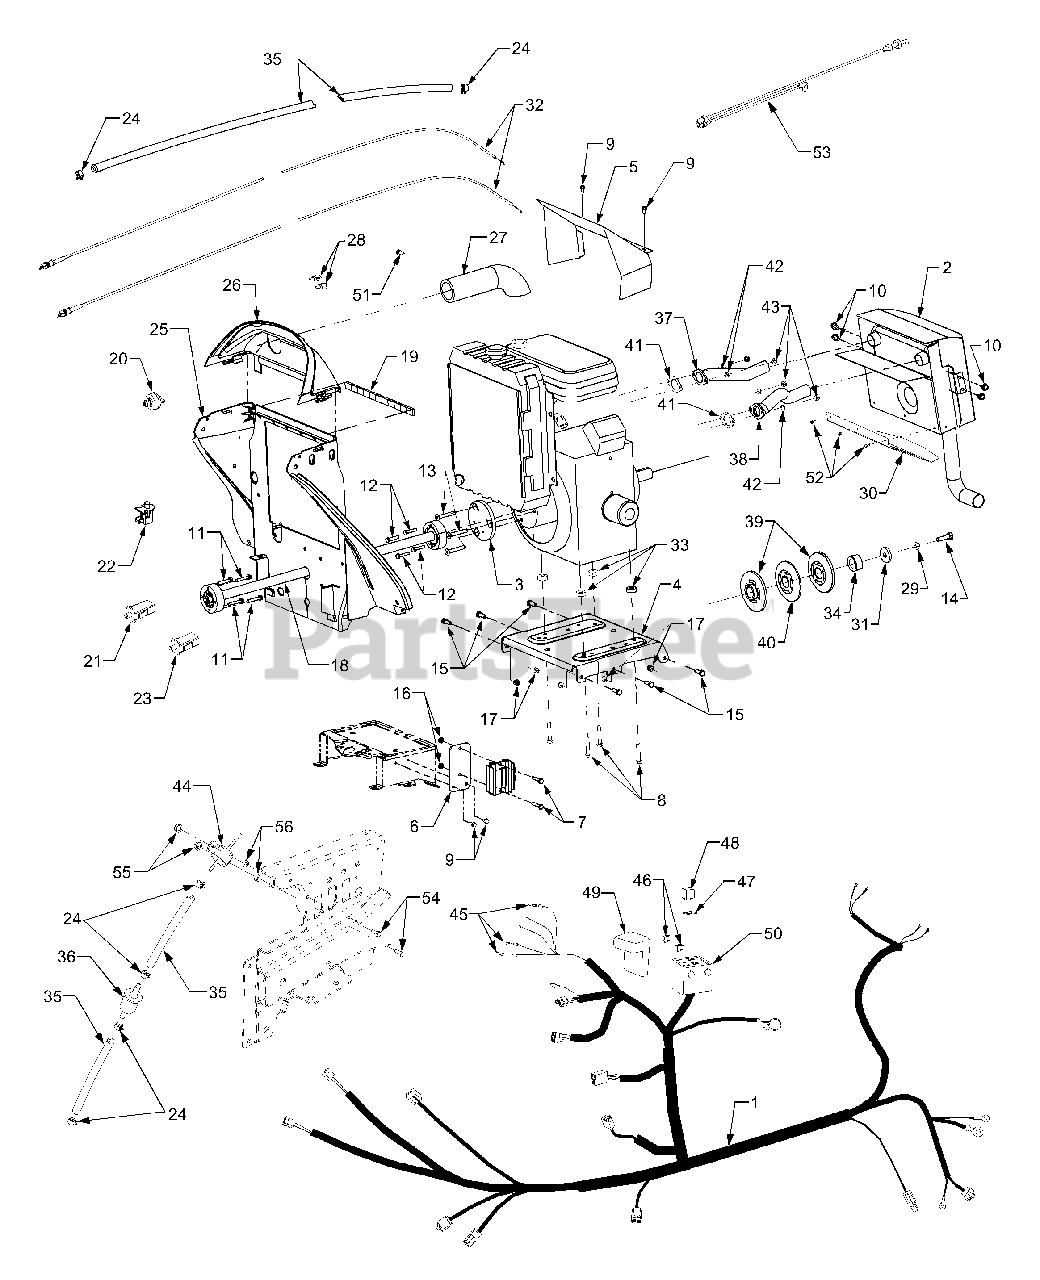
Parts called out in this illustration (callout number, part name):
1	Harness, Wire
2	Muffler Assembly
3	Plate, Coupling Adapter
4	Plate, Engine Mounting
5	Shield, Muffler Heat
6	Plate, Regulator Mounting
7	Screw, Hex Cap 1/4-20 x 1.25 GR5
8	Screw, Hex Cap M8-1.25 x 25 GR8.8
9	Screw, Hex Wash. Hd. Tapp 1/4-20 x .5
10	Screw, Hex Wash. Hd. Tapp 5/16-18 x .5
11	Screw, Hex Cap, Lock 1/4-20 x 1.25 GR5
12	Screw, Hex Cap, Lock 1/4-20 x 1.25 GR5
13	Screw, Cntrsnk Machine M8-1.25 x 55MM
14	Screw, Hex Cap M10-1.5 x 35MM
15	Screw, Hex Cap 5/16-18 x .875 GR5
16	Nut, Hex Sems, 1/4-20
17	Nut, Hex Insert Lock 5/16-18
18	Shaft, Drive, 27.75 Long
19	Foam Tape
20	Switch, Key
21	Switch, Plunger
22	Switch, Snap Mount
23	Switch, Plunger
24	Clamp, Hose
25	Baffle, Lower Air
26	Baffle, Upper Air
27	Hose, Intake
28	Clip, Fuel Line Retainer
29	Washer, Lock, 7/16
30	Shield, Lower Exhaust
31	Washer, Flat .417 x 1.5 x .225
32	Cable, Choke and Throttle Control
33	Spacer, Engine 1.0 O.D, x .34 Lg
34	Spacer, Crankshaft
35	Fuel Line, 12 inches (Fuel Tank to Filter & Filter to Pump)
35	Fuel Line, (Fuel Pump to Engine)
36	Filter, Fuel
37	Pipe, Exhaust
38	Pipe, Exhaust
39	Pulley Half
40	Pulley, Center
41	Gasket, Exhaust
42	Washer, Lock, 6MM
43	Nut, Hex, 6MM
45	Bulb, Indicator
46	Fuse, 25 Amp
47	Gasket, Silicone
48	Relay, PTO
49	Cover, Fuse Box
50	Box, Fuse
51	Screw, Engine Ground M8-1.25 x 16
52	Screw, Hex Wash. Hd. Tapp #12-24 x .375
53	Hose, Vacuum
54	Screw, Hex Cap 1/4-20 x .88
55	Nut, Hex Flange Lock 1/4-20
56	Spacer, .320 x .56 x .36
